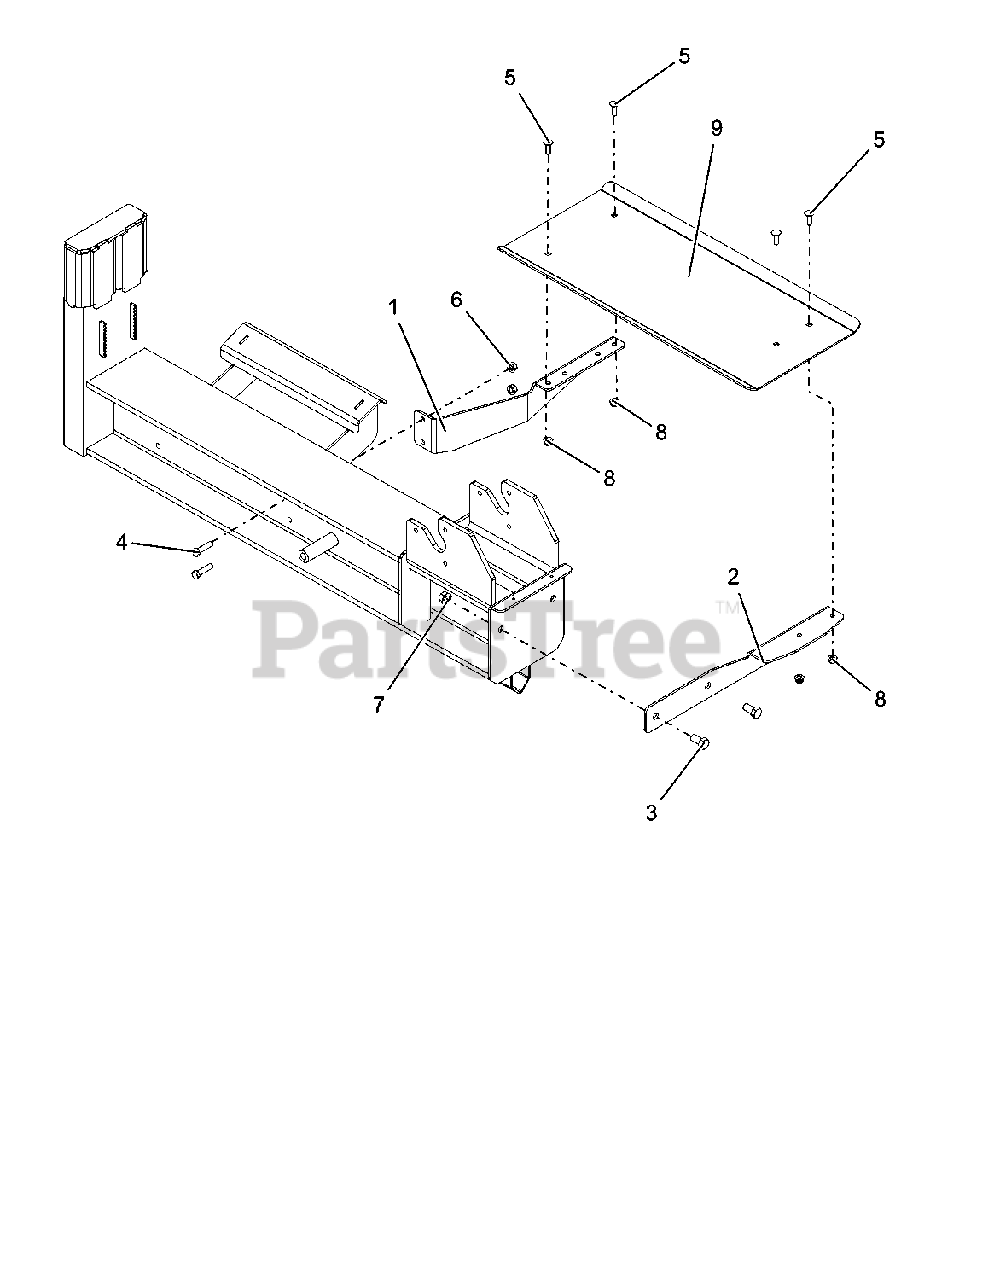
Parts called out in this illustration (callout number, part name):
1	BRKT, MOUNT -REAR TABLE
2	BRKT, MOUNT - FRONT TABLE
3	BLT-HEX .50-13X1.00 GR5 YWZC
4	BLT-HEX .38-16X1.50 GR5 YWZC
5	BLT-RDHDSQSHNK .31-18X1.00 G5YWZC
6	NUT, LK-TOP-FLG .38-16 YWZC
7	NUT, LK-TOP-FLG .50-13 YWZC
8	NUT-LK-NYL-FLG .31-18 YWZC
9	TABLE, WORK - LOG SPLITTER
